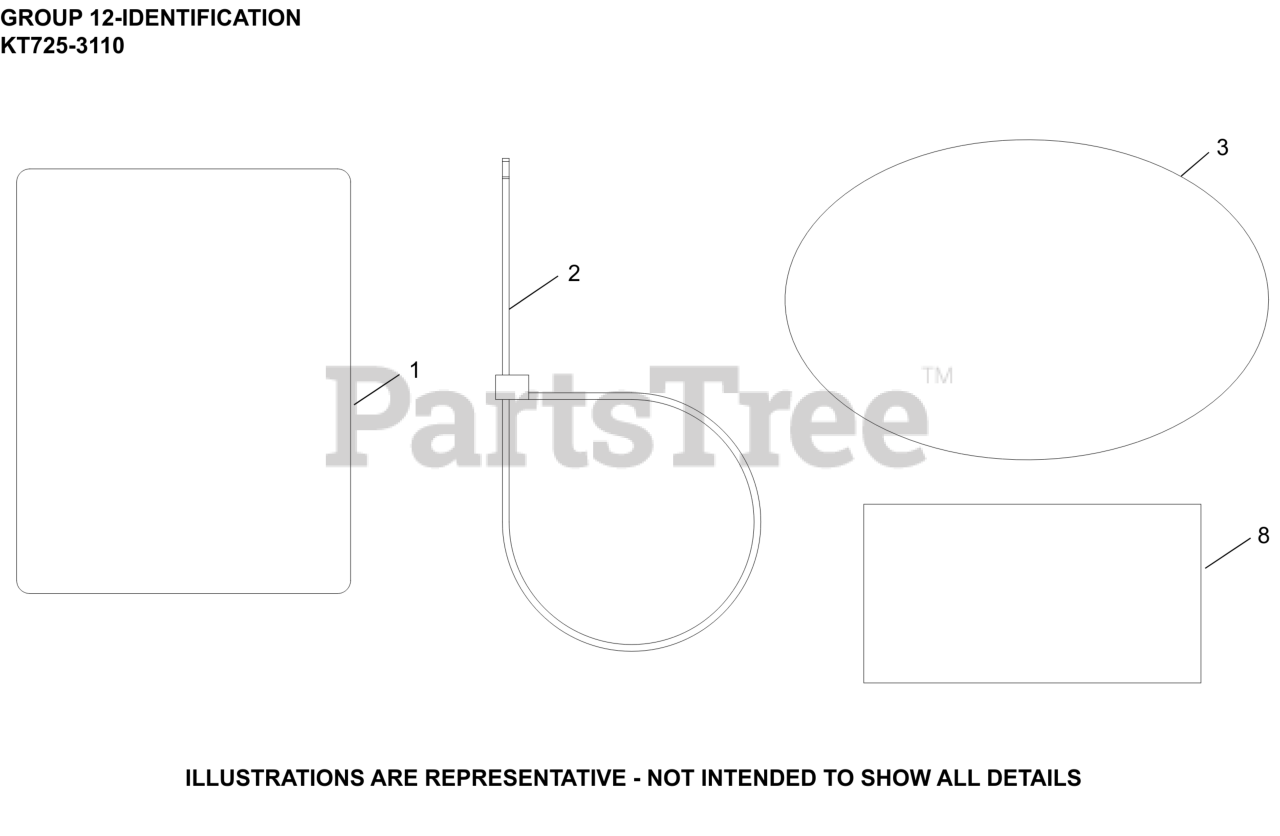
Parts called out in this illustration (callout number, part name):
1	LABEL, CLEAR LAMINATION
3	LABEL, 7000 SERIES KT725 (22 HP)
8	DECAL, USA
